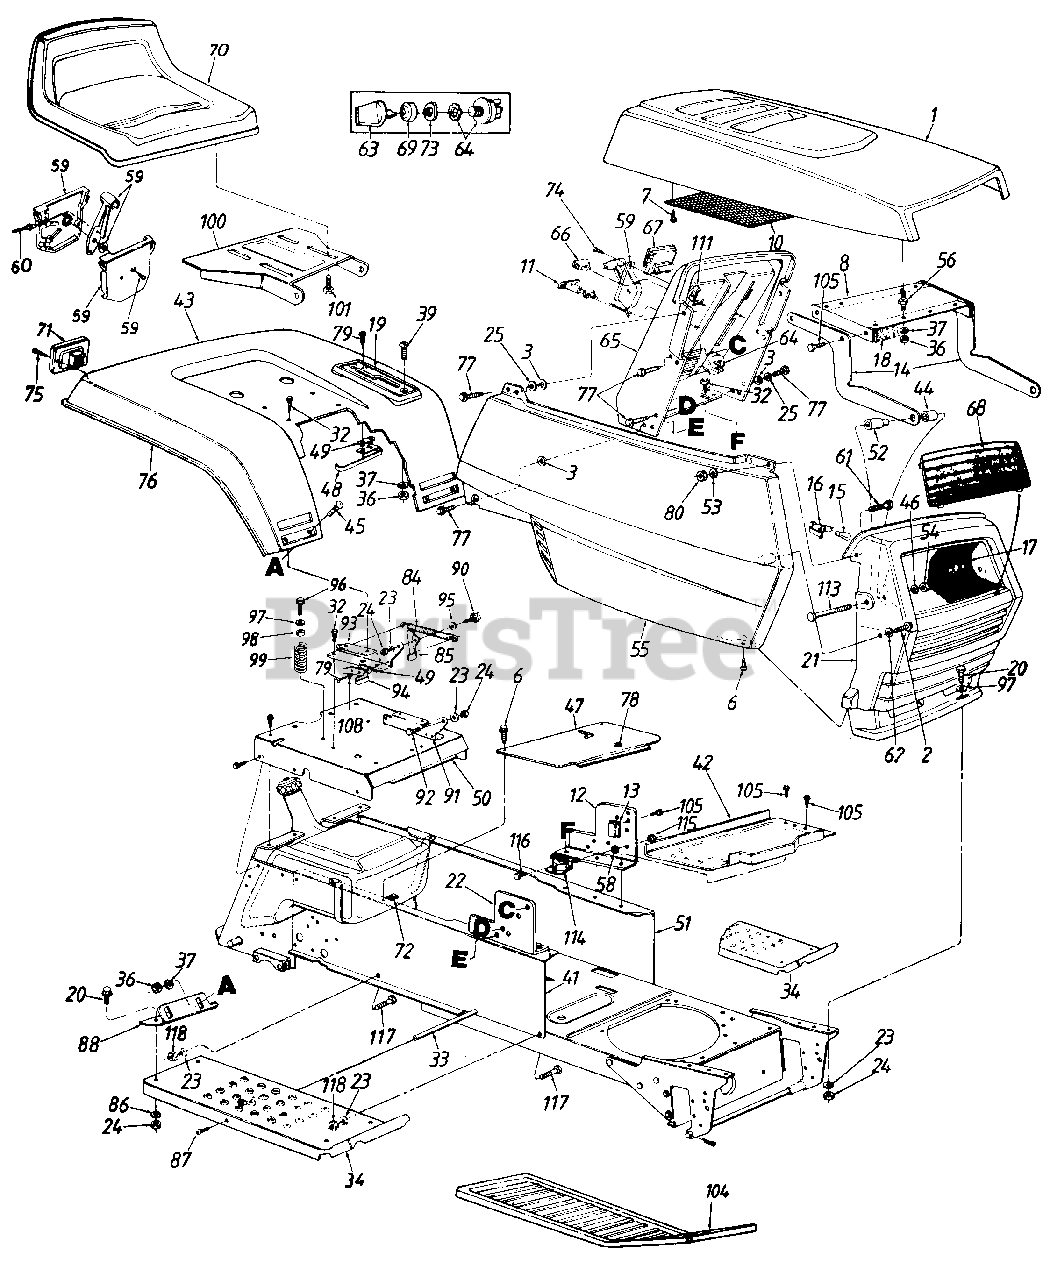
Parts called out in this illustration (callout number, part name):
3	Bolt Retainer 1/4" I.D.
6	Truss Mach. B-Tap Scr. #10 x .5" Lg.
7	Hex Wash Hd. AB-Tap Scr. #8 x .5" Lg.
8	Hood Plate
11	Choke Control
12	Dash Support Brkt.-L.H.
13	Circuit Breaker
14	Hood Hinge
15	Lamp
16	Twist Lock-Lamp Socket
17	Reflector-Headlight
19	Speed Control Index Brkt.
20	Hex Bolt 5/16-18 x .75" Lg.*
23	L-Wash. 5/16" I.D.
24	Hex Nut 5/16-18 Thd.*
25	Fl-Wash. 1/4" I.D. x .93" O.D.
32	Hex Wash. Hd. AB-Tap Scr. 5/16 x .75" Lg.
33	Running Board Rod
37	L-Wash. 1/4" I.D.
39	Truss Mach. Scr. 1/4-20 x .62" Lg.
41	R.H. Side Frame
42	Battery Carrier
45	Carriage Bolt 1/4-20 x .50" Lg.
46	Fl-Wash. .328" I.D. x .68" O.D.
47	Transmission Panel
48	Reverse Safety Switch
49	Insulator Nut Plate
50	Seat Plate
51	L.H. Side Frame
52	Shld. Spacer .33" I.D.
53	Fl-Wash. .281" I.D. x .5" O.D.
54	Hex Cent. L-Nut 5/16-18 Thd.
55	Side Cover-R.H.
56	Double Ended Stud 1/4-20 Thd.
58	Ext. L-Wash. 1/4" I.D.
59	Throttle Control Box Ass'y.
60	Throttle Control Wire 35" Lg.
61	Hex Bolt 1/4-20 x .62" Lg.
62	Fl-Wash. .281" I.D. x .73" O.D.
64	Ignition Switch
66	Light Switch
67	Ammeter
68	Lens
69	Ignition Switch Cap
71	Taillight Ass'y.
72	Speed Nut #10Z
73	Ignition Switch Nut
74	Truss Mach. AB-Tap Scr. #10 x .5" Lg.
75	Truss Hd. AB-Tap Scr. #6 x .62" Lg.
76	Trim Strip-81"
77	Hex Wash. Hd. Tap Scr. 1/4 x.75" Lg.
78	Snap Bushing
79	Hex Wash. Hd. AB-Tap Scr. #8 x .50" Lg.
80	Hex L-Nut 1/4-20 Thd.
84	Ext. Spring 5.31" Lg.
85	Seat Lift Brkt.
86	Bell-Wash. .345" I.D. x .88" O.D.
87	Truss Machine Scr. 5/16-18 x .75" Lg.
91	Seat Pivot Brkt. Support-L.H.
92	Shld. Bolt .437" Dia. x .162"
93	Seat Pivot Brkt. Support-R.H.
94	Spring Switch
95	Spr.-Wash..445" I.D.
96	Hex Wash. Hd. Tap Scr. 5/16-18 x .75" Lg.
97	Fl-Wash. .344" I.D.
99	Compression Spring
100	Seat Pivot Bracket
101	Hex Tap Scr. 3/8-16 x .75"
105	Hex Tap Scr. 1/4-20 x .5" Lg.
108	Fiber Washer
111	Speed Nut 1/4-20 Thd.
113	Hex Bolt 5/16-18 x 2.75"
114	Solenoid
115	Hex Sems Nut 1/4-20 Thd.
116	Hex Bolt 1/4-20 x .5" Lg.
117	Rib Neck Bolt 5/16-24 x .75" Lg.
118	Hex Nut 5/16-24 Thd.
